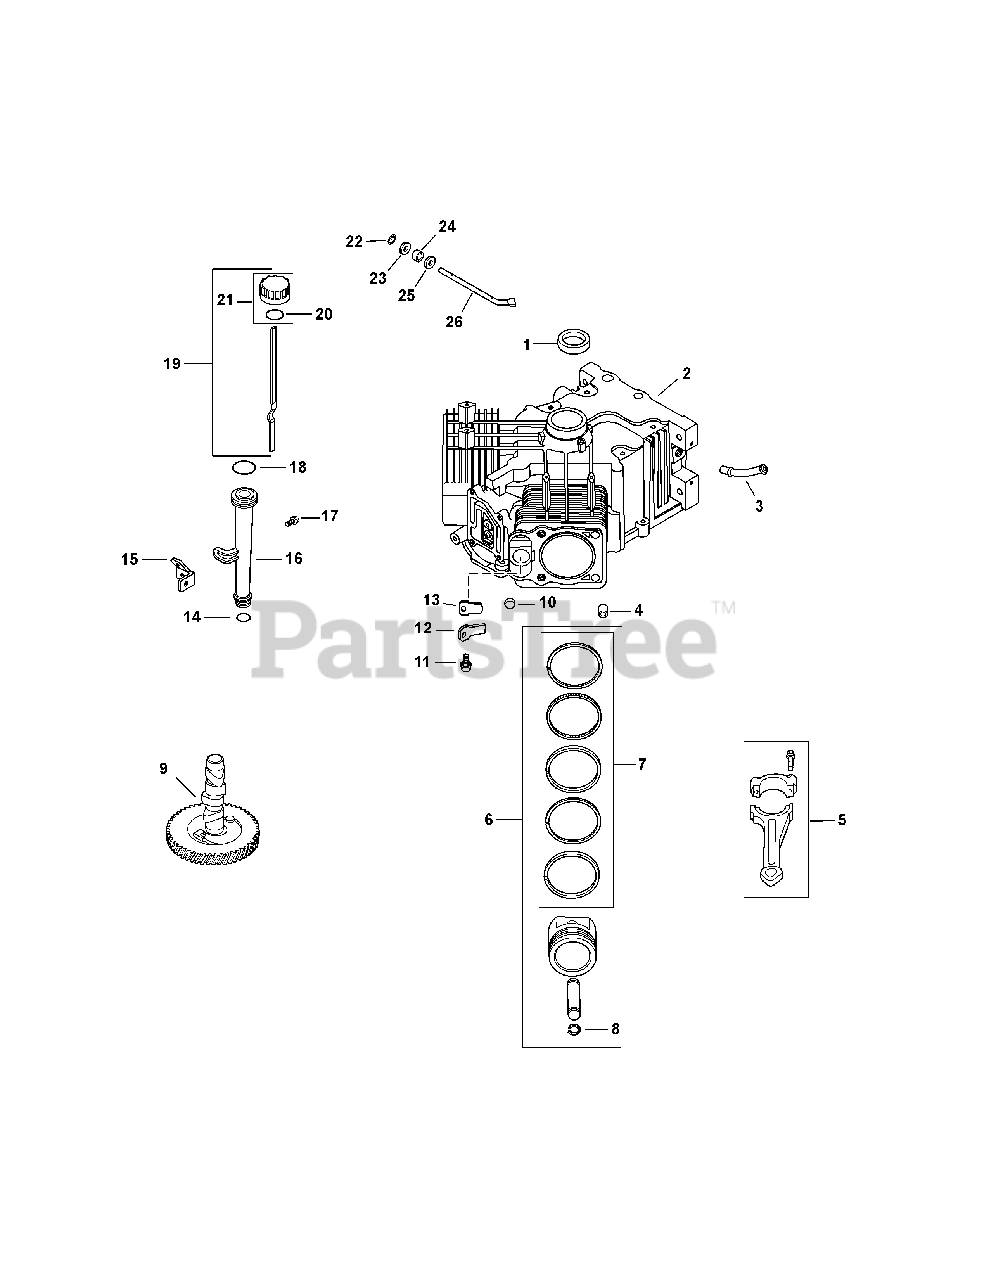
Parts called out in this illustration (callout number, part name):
1	SEAL, OIL (HELIX LIP)
2	CRANKCASE
4	PIN, LOCATING
5	ROD, ASSEMBLY CONNECTING (STD)
5	ROD, ASSY CONNECTING (.25 O.S.)
6	PISTON ASSY W/RING SET (STD) (includes 7, 8)
6	KIT,PISTON ASSY W/RING SET (.08)
6	KIT,PISTON ASSY W/RING SET (.25)
6	PISTON ASSY W/RING SET (.5)
7	RING SET, PISTON (STD)
7	RING SET, PISTON (.08)
7	RING SET, PISTON (.25)
7	RING SET, PISTON (.50)
8	RETAINER, PISTON PIN
9	KIT, CAMSHAFT
11	SCREW, FLG THD FRM M5X.8X10
12	RETAINER, BREATHER REED
13	REED, BREATHER
14	O-RING, LOWER OIL FILL TUBE
15	BRACKET, OIL FILL TUBE
16	TUBE ASSEMBLY
17	SCREW, FLG THD FRM M5X0.8X16
18	O-RING, UPPER OIL FILL TUBE
19	DIPSTICK, ASSY(includes 20, 21)
20	O-RING, DIPSTICK
21	KIT, OIL FILL CAP (YELLOW) (Includes 20)
22	RETAINER, RING
23	WASHER, FLAT 9 MM
24	SEAL, GOVERNOR CROSS SHAFT
25	WASHER, FLAT 11/32''
26	SHAFT, GOVERNOR CROSS
